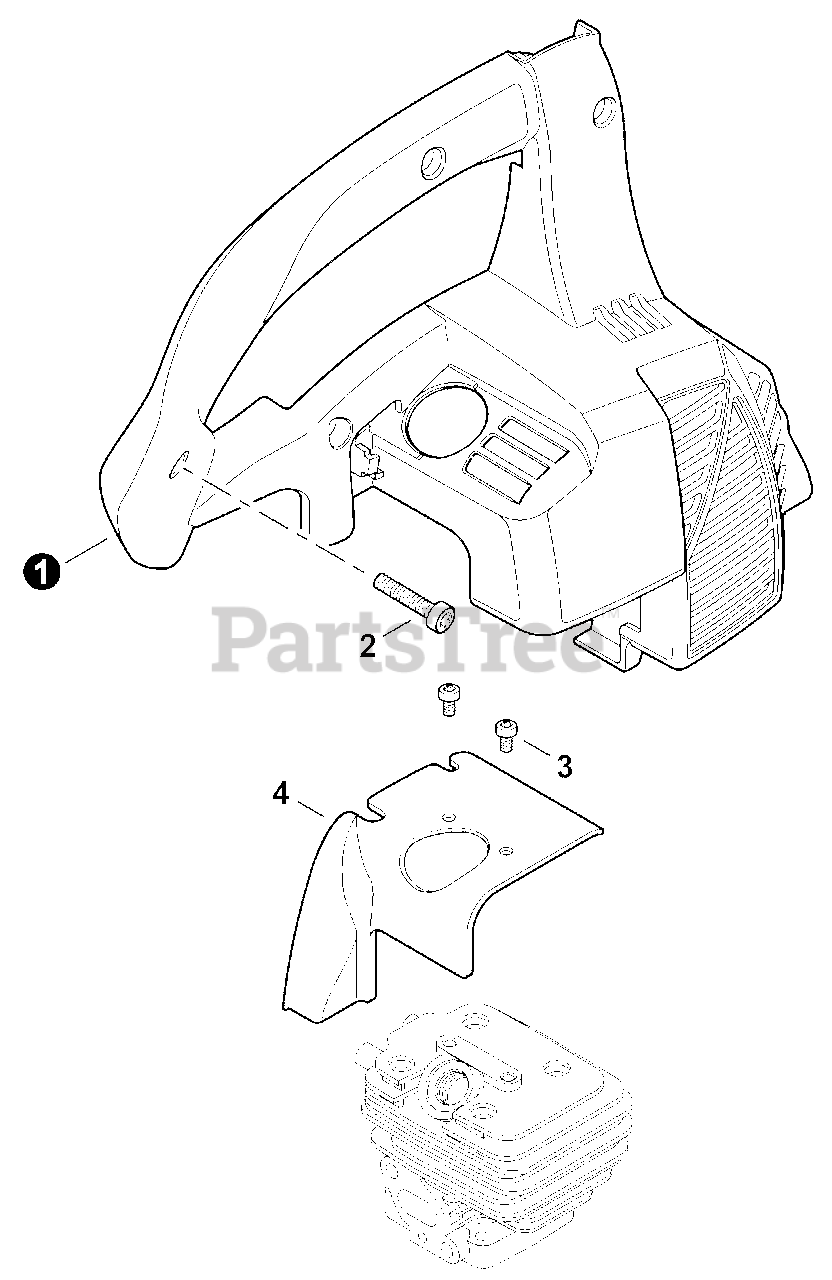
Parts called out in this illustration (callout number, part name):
1	COVER, ENGINE
2	BOLT, TORX 5×20
3	BOLT, TORX 5×8
4	SHIELD, CYLINDER
